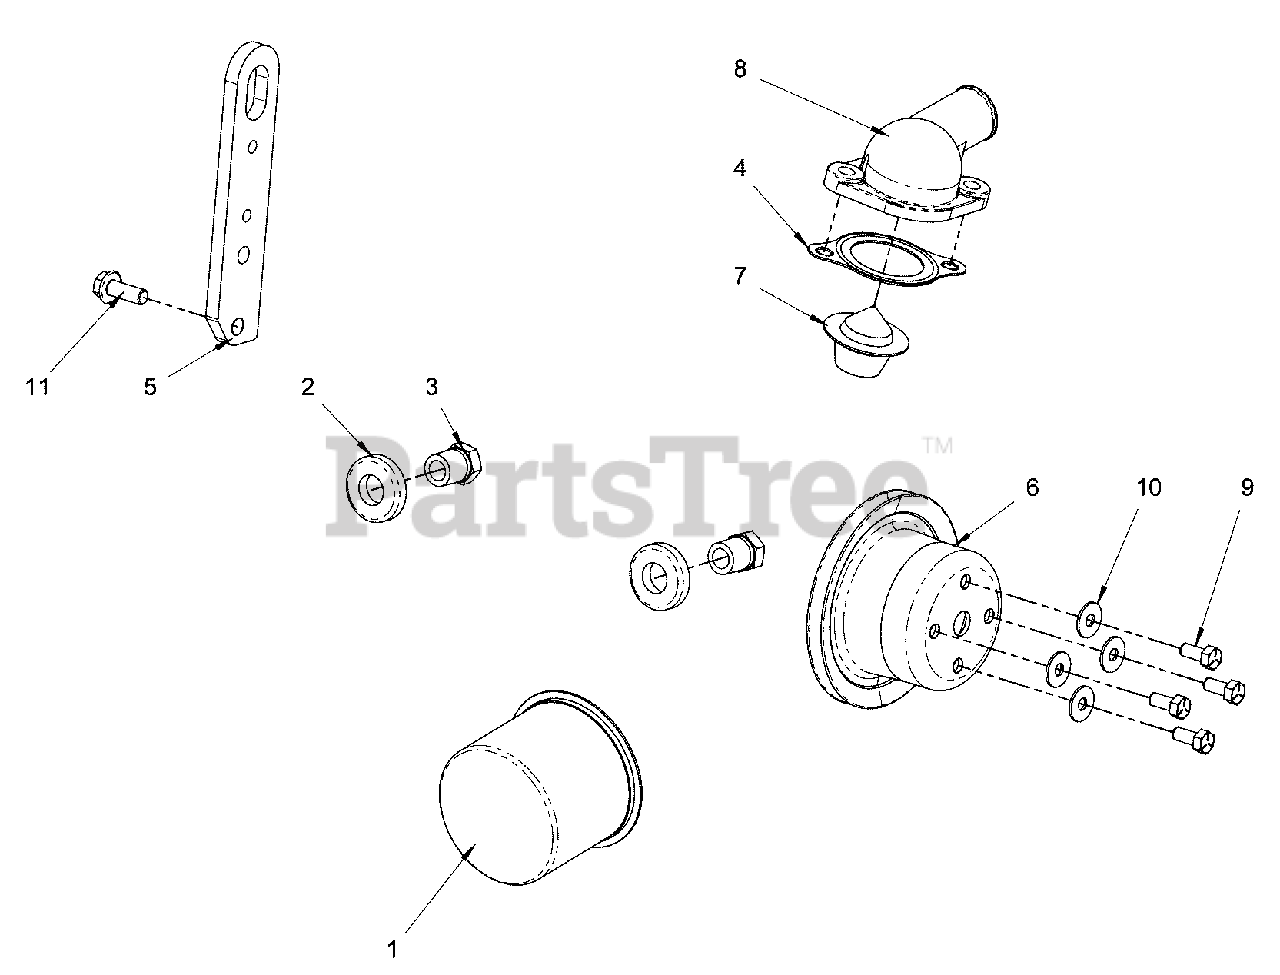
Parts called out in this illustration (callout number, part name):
2	* ADAPTER
3	* PLUG
5	* LIFT EYE
6	HI FAN PULLEY
9	* BOLT
10	* WASHER
11	* BOLT
